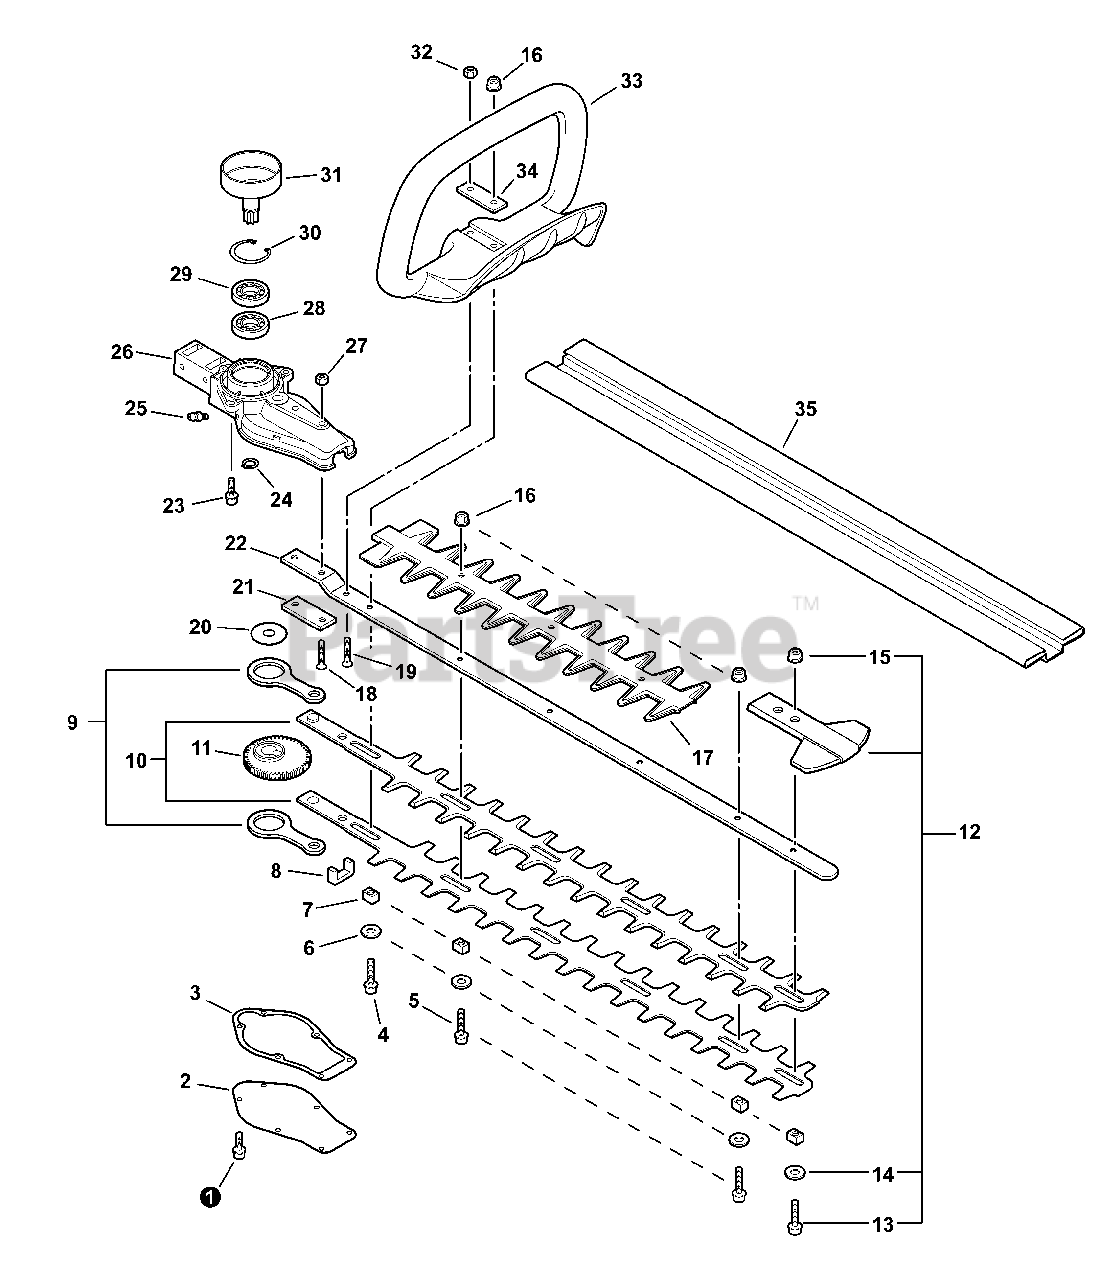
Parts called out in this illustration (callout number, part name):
1	SCREW - 4×10
2	LID, GEAR CASE
3	GASKET, GEAR CASE
4	SCREW - 5×40
5	SCREW - 5×20
6	WASHER - 6
7	GUIDE, BLADE
8	SEAL, FELT
9	ROD, CONNECTING
10	BLADE, TRIMMER - 20"
11	GEAR - DRIVE
12	TIP GUARD KIT
13	SCREW - 5×20
14	WASHER - 6
15	LOCKNUT - 5
16	LOCKNUT - 5
17	PROTECTOR, BLADE
18	SCREW - 6×25
19	SCREW - 5×30
22	SUPPORT, BLADE
23	SCREW - 5×20
24	RING, RETAINING - 14
25	FITTING, GREASE
26	CASE, GEAR
27	LOCKNUT - 6
28	BEARING, BALL - 6202
29	BEARING, BALL - 6202
30	RING, RETAINING - 35
31	DRUM, CLUTCH
32	LOCKNUT - 5
33	HANDLE - FRONT
35	COVER, BLADE - 20" (50cm)
